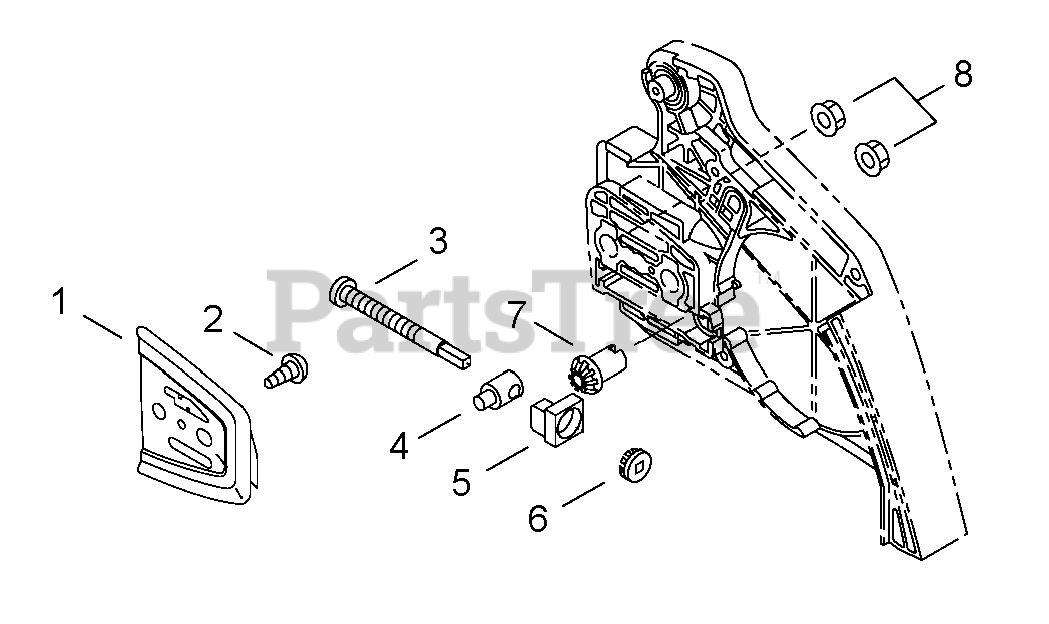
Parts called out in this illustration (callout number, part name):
1	PLATE, GUIDE - INNER
2	SCREW - 4X12 -- TAPPING
3	SCREW, TENSIONER
4	TENSIONER, CHAIN
5	COLLAR - 8
6	GEAR - BEVEL
7	GEAR - PINION
8	NUT - 8X1.25 -- FLANGE
